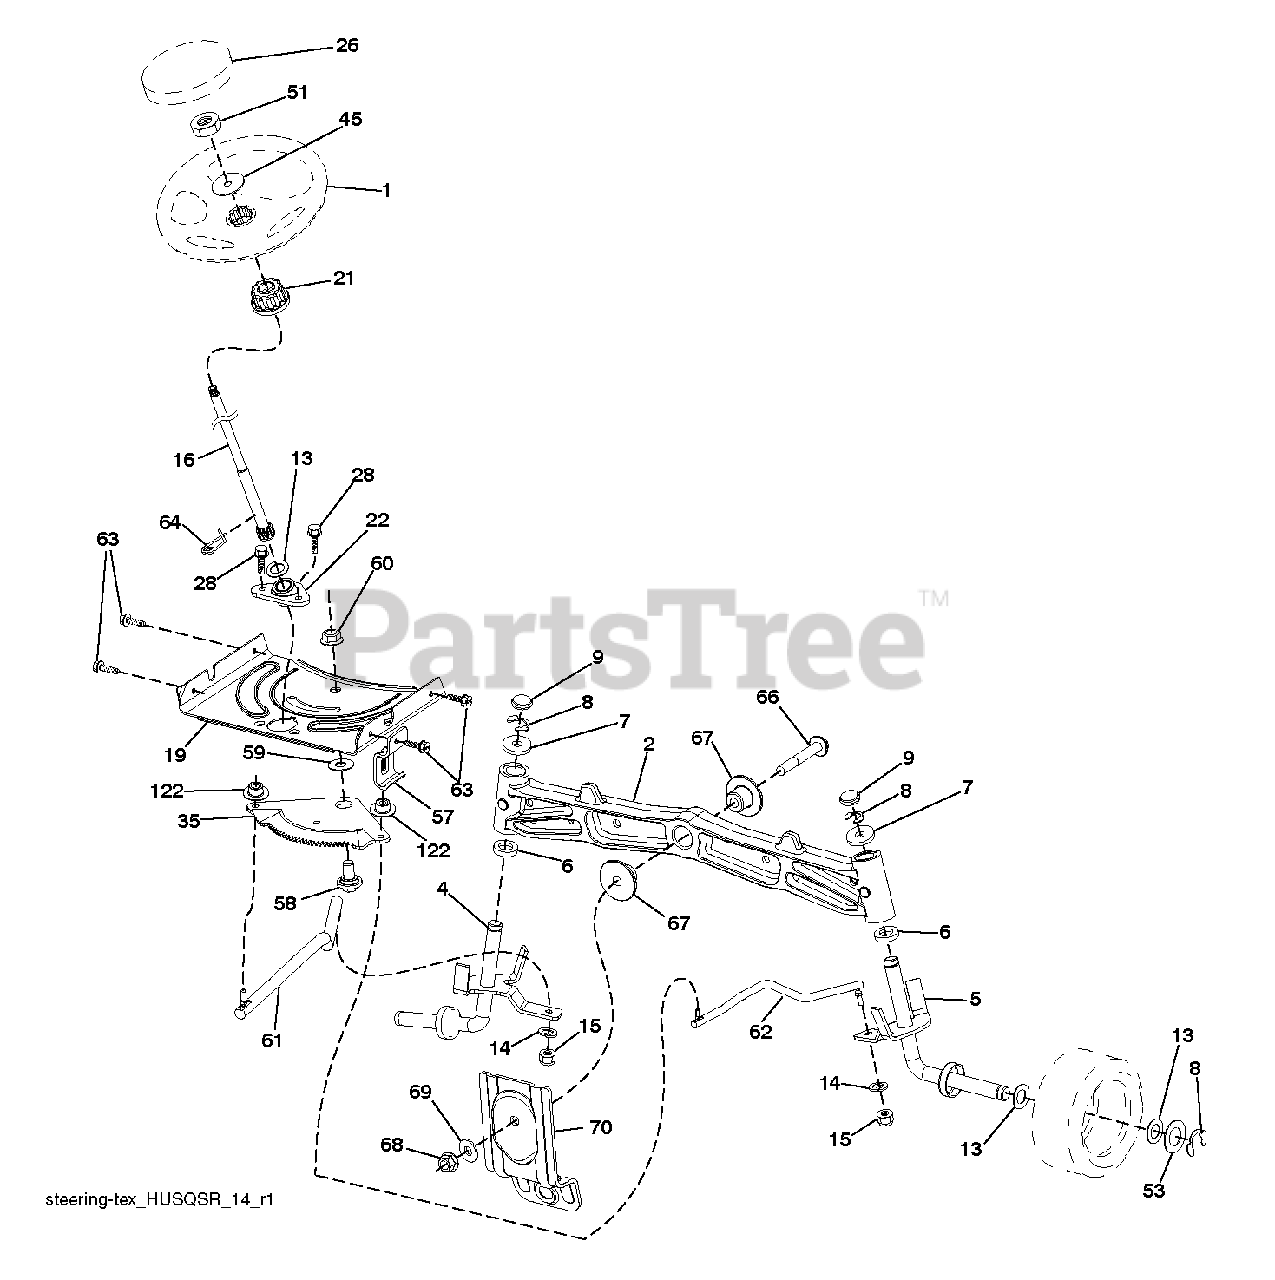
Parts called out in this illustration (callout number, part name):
1	WHEEL.STEER.HUSQ.SR.498.OVMLD
2	AXLE.CAST.IRON
4	SPINDLE.WELDED.LH.15"TEX
5	SPINDLE.WELDED.RH.15"T
6	THRUST WASHER
9	CAP.SPINDLE.BLACK
14	WASHER, LOCK 3/8
15	NUT CROWNLOCK 3/8-24
16	SHAFT, STEERING
19	PLATE.STEER.DDL.NLT/NG
21	ADAPTER, WHEEL STNG..
22	STEERING.SUPT.LOWER.
26	INSERT.CAP.WHL.STRG.HUSQ.PREM
28	SCREW, 3/8-16X3/4
35	GEAR.SECTOR.PLATE.DDL.
45	WASHER 9/16"ID, 2 3/8"OD
51	NUT.HEX.1/2-20
53	WASHER.HARDENED
57	BRKT.UPSTOP.GT/LT.TEX
58	BOLT.SHOULDER.SECTOR.P
59	WASHER.THURST.SECTOR.S
60	NUT FLANGE LOCK 5/8-11
61	DRAGLINK.LH.BALLSTUD.D
62	DRAGLINK.RH.BALLSTUD.D
63	SCREW
64	RETAINER.CLIP.SPRING.S
66	BOLT HEX FGHD 7/16-14 X 3 SERR
67	BUSHING.PM.FRONT AXLE
68	NUT.LOCK.FLANGE.7/16
69	WASHER.1.5X.505X.118
70	BRKT.DECK.SUSPENSION.F
122	CAP.GEAR.SECTOR.TEX
